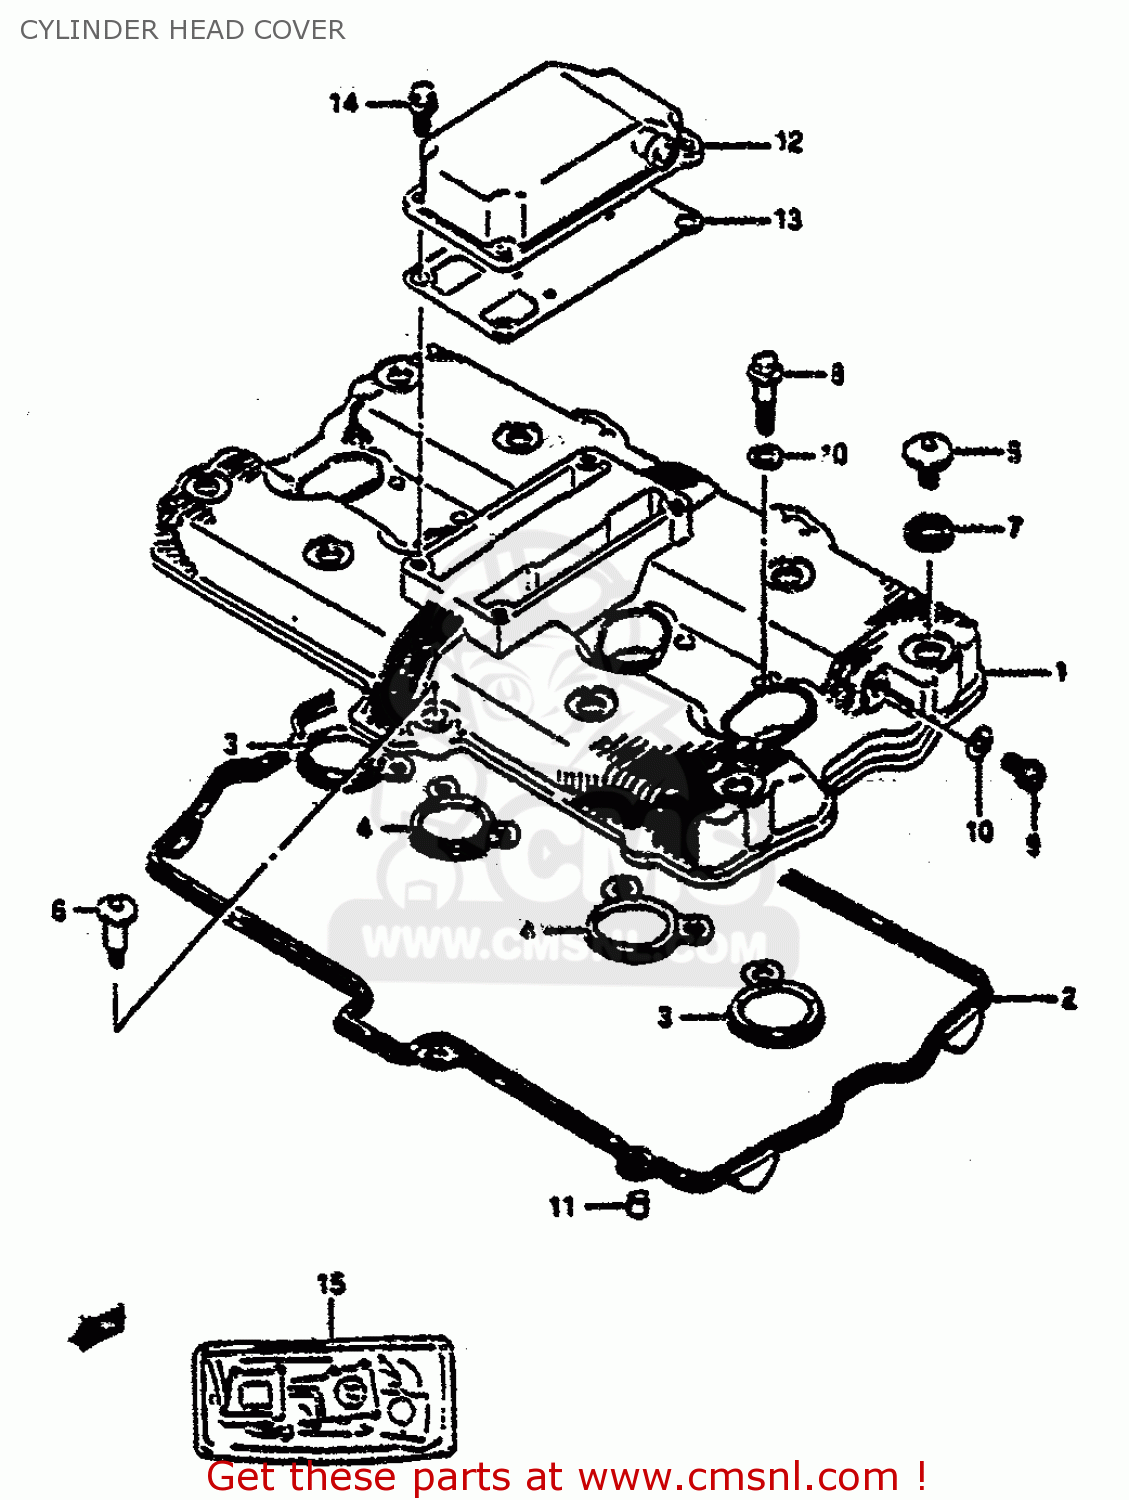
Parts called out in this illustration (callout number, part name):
1	COVER,CYLINDER HEAD
2	GASKET,CYLINDER HEAD COVER (NAS)
3	GASKET,HEAD COVER NO.2 (NAS)
4	GASKET,HEAD COVER NO.3 (NAS)
5	BOLT(7X17.5)
6	BOLT(7X31)
7	WASHER(10.6X25.5X2.3)
8	BOLT,UNION 8X35
9	PLUG, HEAD COVER
10	GASKET 8.2X14X1 (NAS)
11	PIN
12	COVER,BREATHER
13	GASKET,BREATHER (NAS)
14	BOLT
15	GASKET SET
